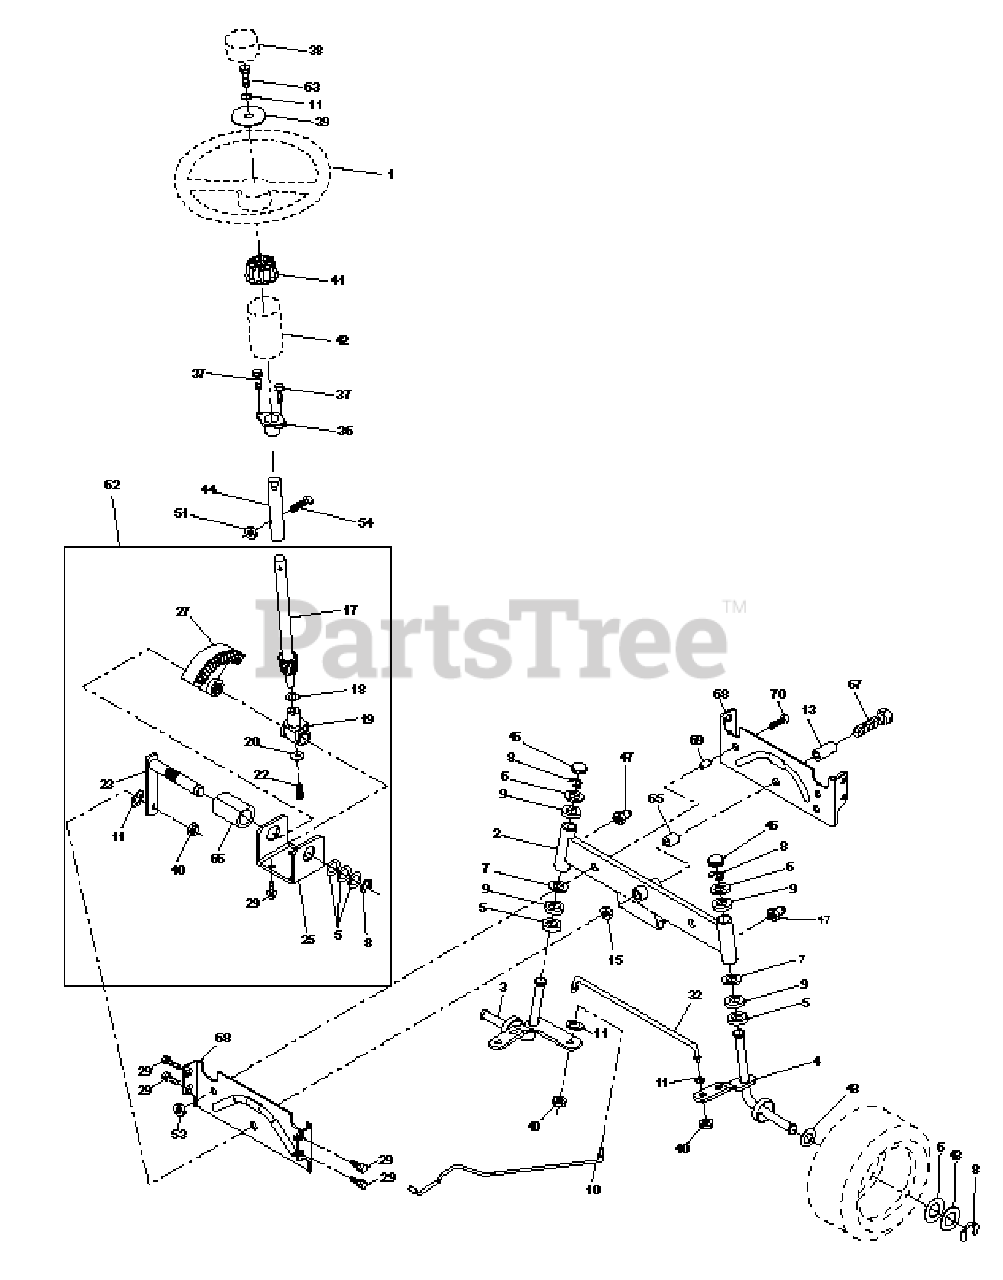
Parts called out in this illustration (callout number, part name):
1	Wheel Steering
2	Axle Front Casting Machined
3	Spindle Asm LH
4	Spindle Asm RH
5	Bearing Race Thrust Harden
6	Washer 25/32 X 1-5/8 X 16 Ga
7	Washer 27/32 X 1-1/4 X 16 Ga
8	Ring Klip #t5304-75
9	Bearing Col Strg Blk
10	Link Drag Extended Cast
11	Washer Lock Hvy Hlcl Spr 3/8
13	Bearing Axle STLT/GT
15	Nut Lock Flange 5/8-11 Unc
17	Shaft Asm Strg
18	Washer Thrust 515x 750x 033
19	Support Shaft
20	Washer Shim 1/4 X 5/8 X 062
22	Screw Cap Sckt Hd Phos & Oil
23	Shaft Asm Pittman
25	Bracket Steering
26	Bushing Link Drag Blk LR
27	Gear Sector
28	Washer 13/32 X 7/8 X 16 Ga
29	Screw Thdrol 3/8-16x3/4 Ty-tt
30	Pin Cotter 1/8 X 3/4 Cad
32	Rod Asm Tie Ball
36	Bushing Strg
38	Insert Cap Strg Wh Au
39	Washer 13/32 X 2-3/8 X 8 Ga
40	Lock nut
41	Adaptor Wheel Strg
42	Boot Steering Shaft
43	Washer 25/32 X 1 1/4 X 16 Ga
44	Extension Steering Shaft LR/LT
46	Cap Spindle Fr Top Blk
47	Fitting Grease
51	Nut Lock Hex w/Ins 5/16-18
53	Nut Crownlock 3/8-16unc
54	Bolt Fin Hex 5/16-18 Unc x 1-1/4
62	Kit, Steering Assembly Svc
63	Bolt Fin Hex 3/8-16unc x 1 Gr. 5
65	Spacer Axle
66	Bearing Arm Pittman
67	Bolt, Fin Hex 5/8-11 UNC x 2-3/4
68	Axle, Brace
69	Spacer Brace Axle
70	Bolt Fin Hex 3/8-16unc x 2-1/4
